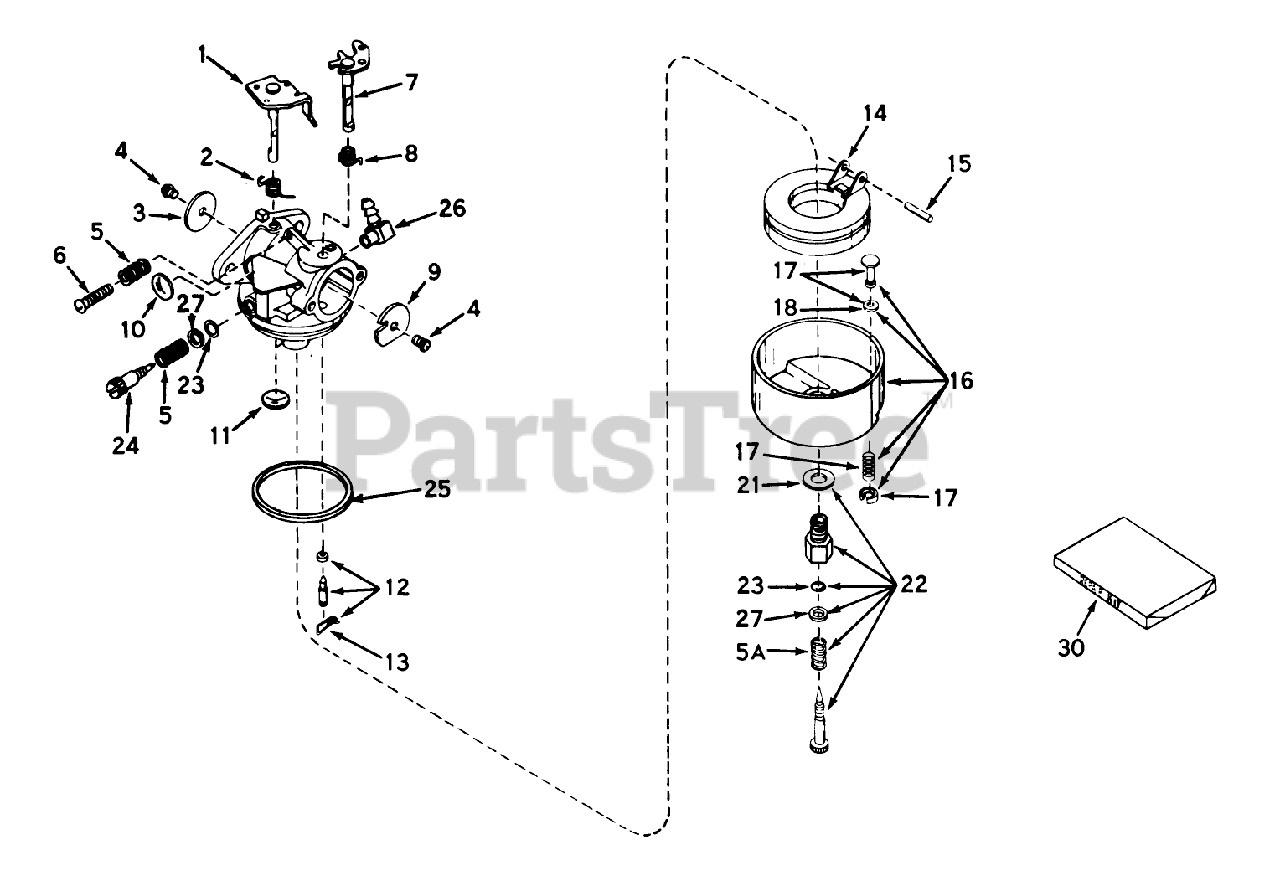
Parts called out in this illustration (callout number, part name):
1	Throttle Shaft and Lever ASM
2	Spring, Throtte Return
3	Shutter-Throttle
4	Screw-Shutter
5	Spring-Tension
5A	Spring
6	Screw-Throttle Crack Screw / Idle Speed
7	Shaft Lever Assy., Choke
8	Spring, Choke return
9	Shutter, Choke
10	Plug-Welch, Idle Mixture Well
11	Plug-Welch, Atmospheric Vent
12	Inlet Needle, Seat Clip Assy. (Incl. No. 13)
13	Clip-Spring
14	Float,Carburetor
15	Shaft-Float
16	Bowl Drain Assy., Float (Incl. No. 17)
17	Bowl Drain ASM
18	Gasket-Plunger, Drain
21	Washer-Bowl Nut
22	Adjustment Screw Assembly, Main (Incl. Nos. 5A, 21, 23 27)
23	ORing
24	Screw, Idle Adj.
25	O Ring-Bowl, Float
26	Fitting, Fuel Inlet
27	Washer
30	Repair Kit
